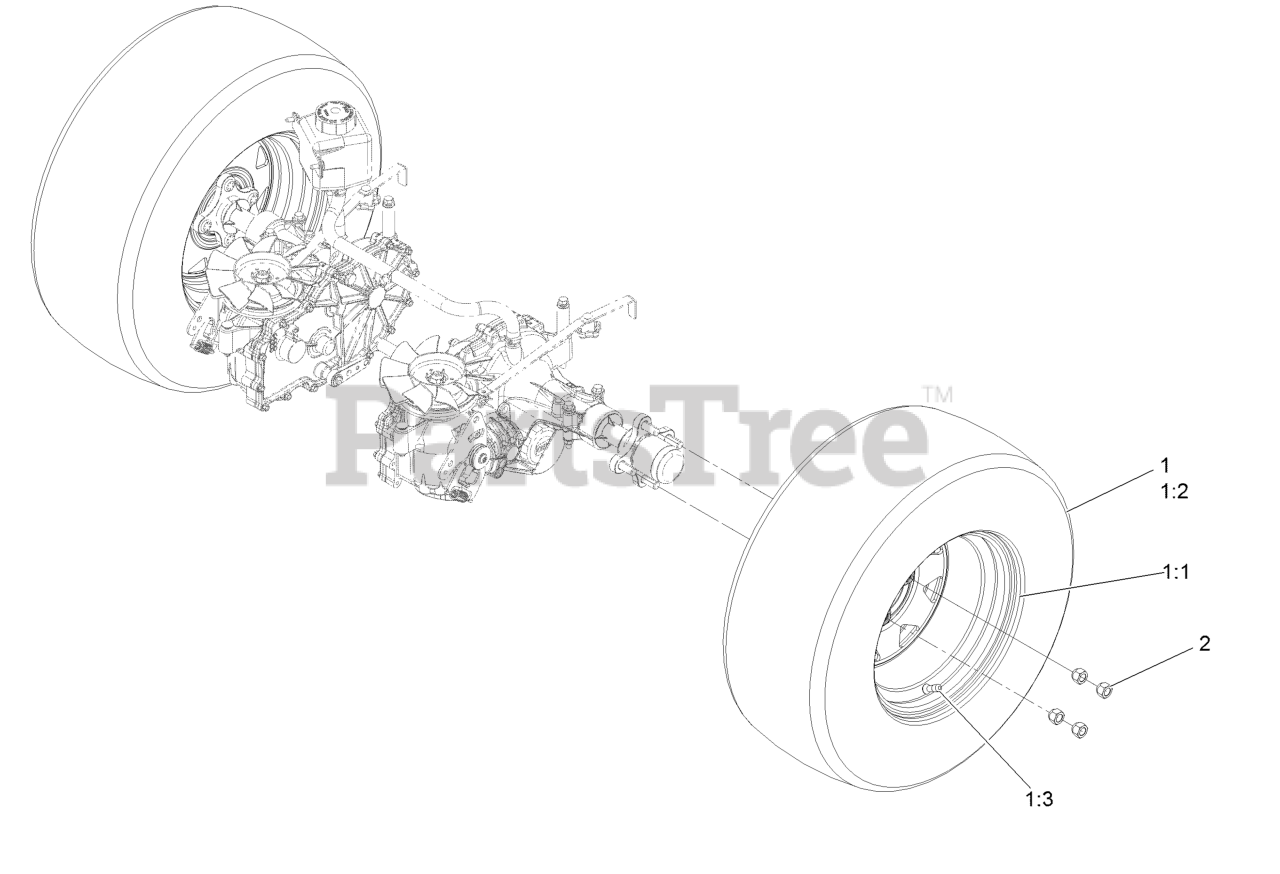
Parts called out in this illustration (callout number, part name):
1	Wheel And Tire ASM
1:3	Stem-Valve
2	Nut-Lug 1/2-20
